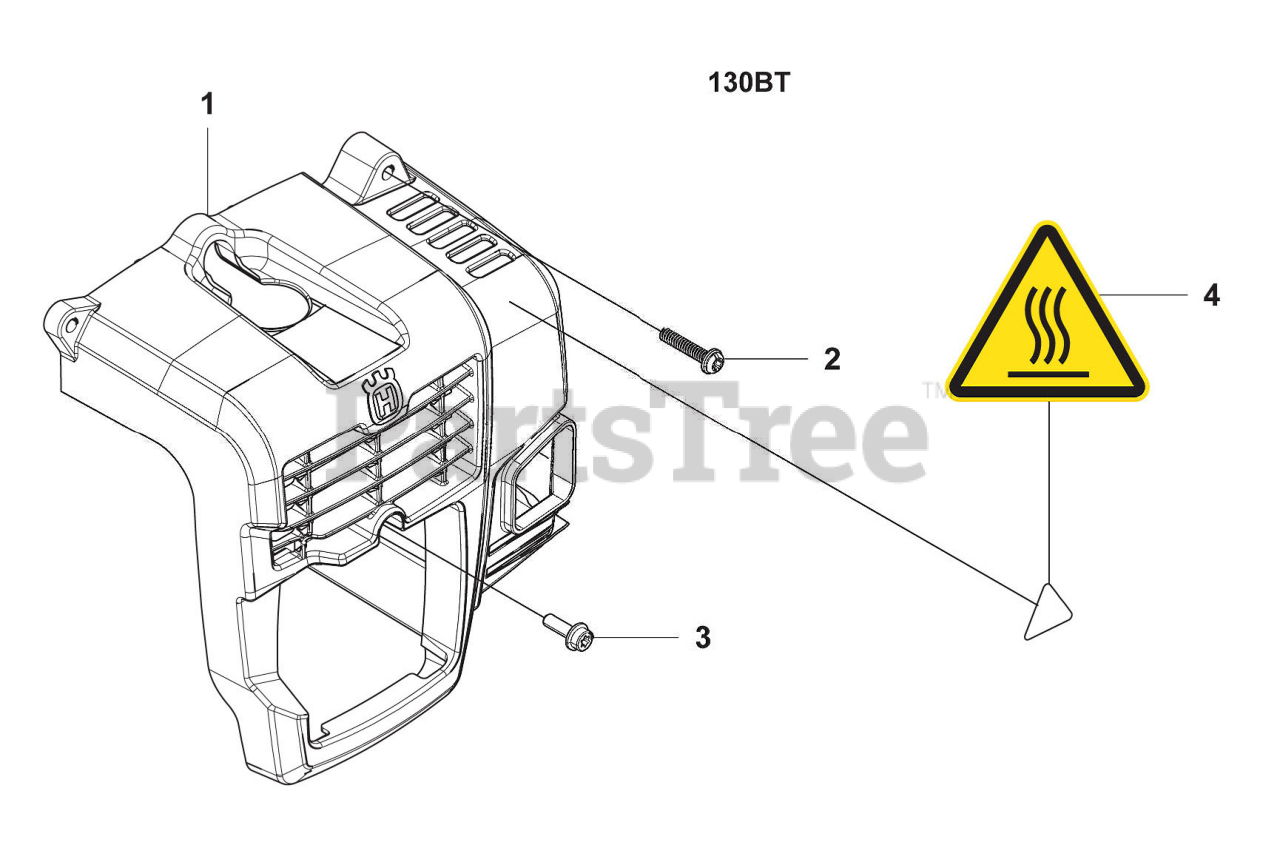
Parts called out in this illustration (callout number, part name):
1	Engine Cover
2	Screw
3	Bolt
4	RP_LABEL, HOTMARK
